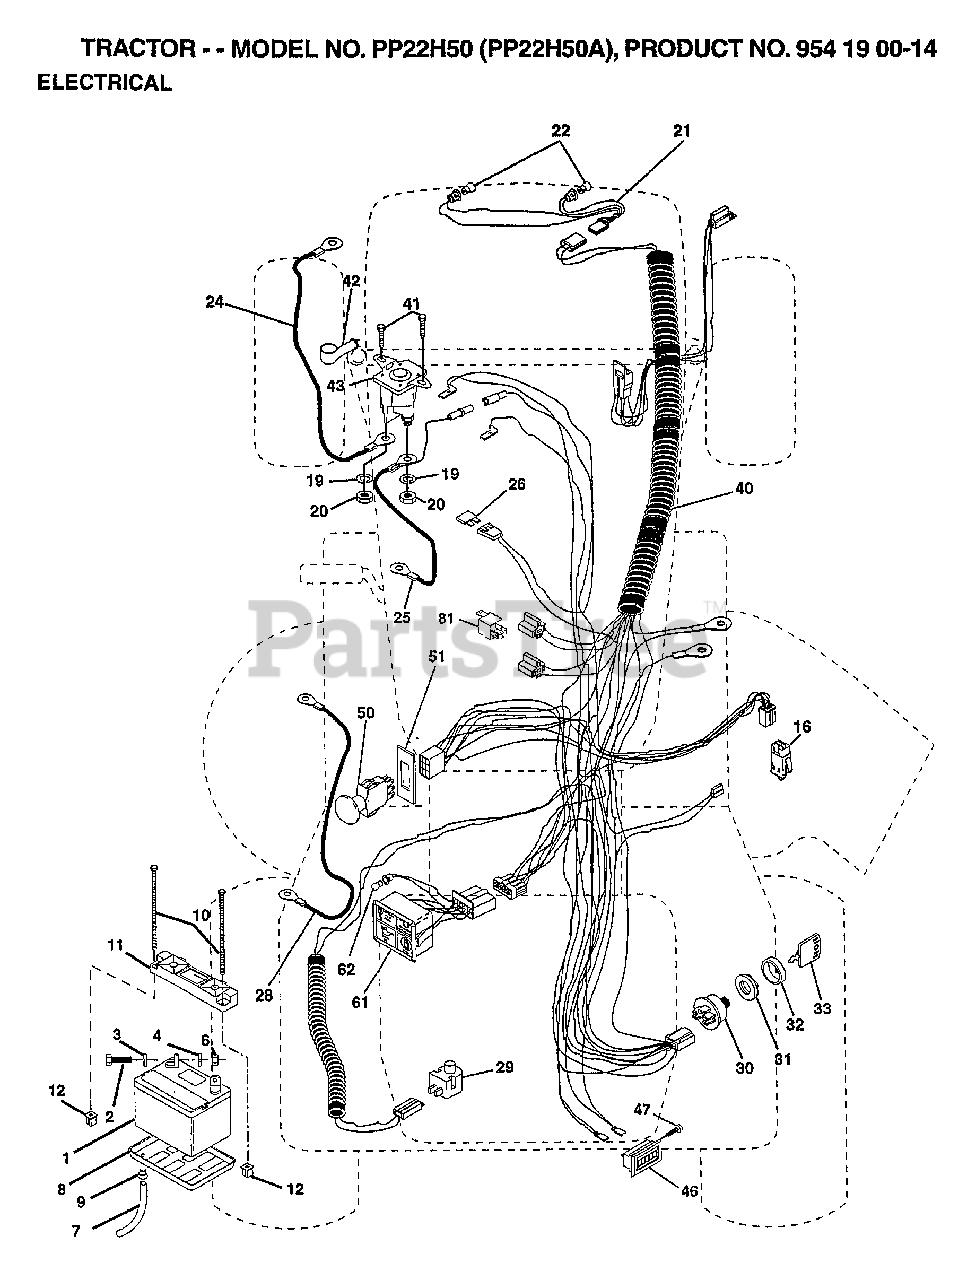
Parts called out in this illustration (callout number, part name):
2	BOLT LT
3	LOCKWASHER
4	WASHER
7	"DRAIN TU T, BATT"
8	"TRAY T, BATTERY"
9	HOSE CLAMP T
11	HOLDDOWN BATTERY
16	SWITCH INTERLOCK
20	NUT
21	"HARNESS,LIGHT SOC"
22	HEADLAMP BULB
24	CABLE.BATY.22.RED
25	CABLE.BATRY.4GA.
26	FUSE HYT
28	"CABLE BATTERY,GRD"
29	SWITCH SEAT
30	SWITCH IGN 4POS
31	NUT IGNITION
32	COVER KEY SWITCH
33	KEY
40	HARNESS IGNITION
41	SCREW
46	HOUR METER T
47	SCREW
50	PTO SWITCH.BLK
51	RING RETAIN PTO
61	LIGHT.PKG.ASM.
62	BULB, LIGHT PKG.
81	RELAY ASSY T
